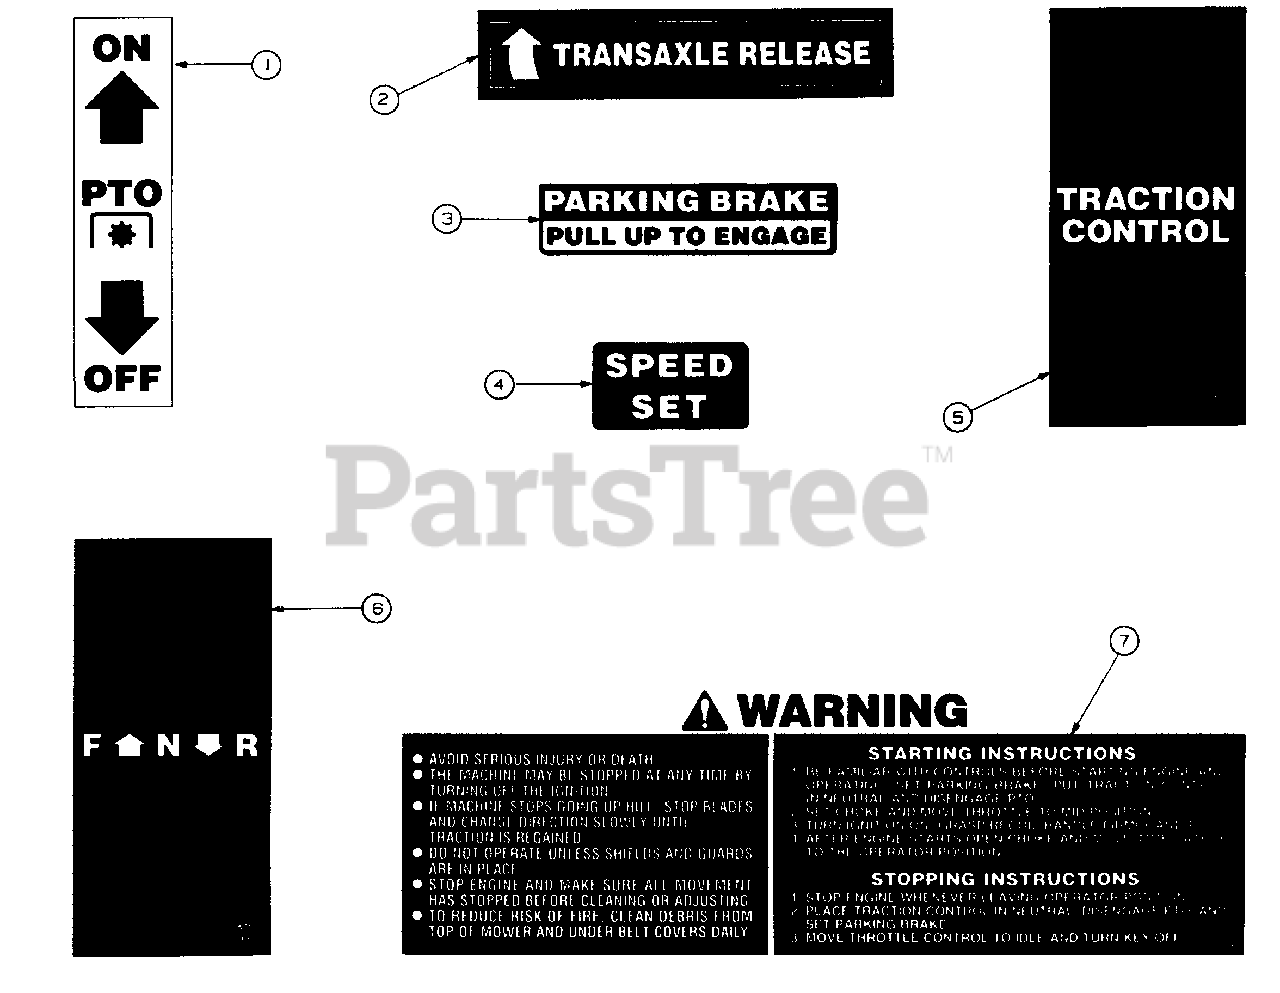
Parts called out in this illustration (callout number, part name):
1	Graphic, Manual PTO
2	Graphic, Transaxle Release
3	Graphic, Park Brake
4	Graphic, Speed Set
5	Graphic, Traction Control
6	Graphic, F-N-R
7	Graphic, Fuel TankWarning
